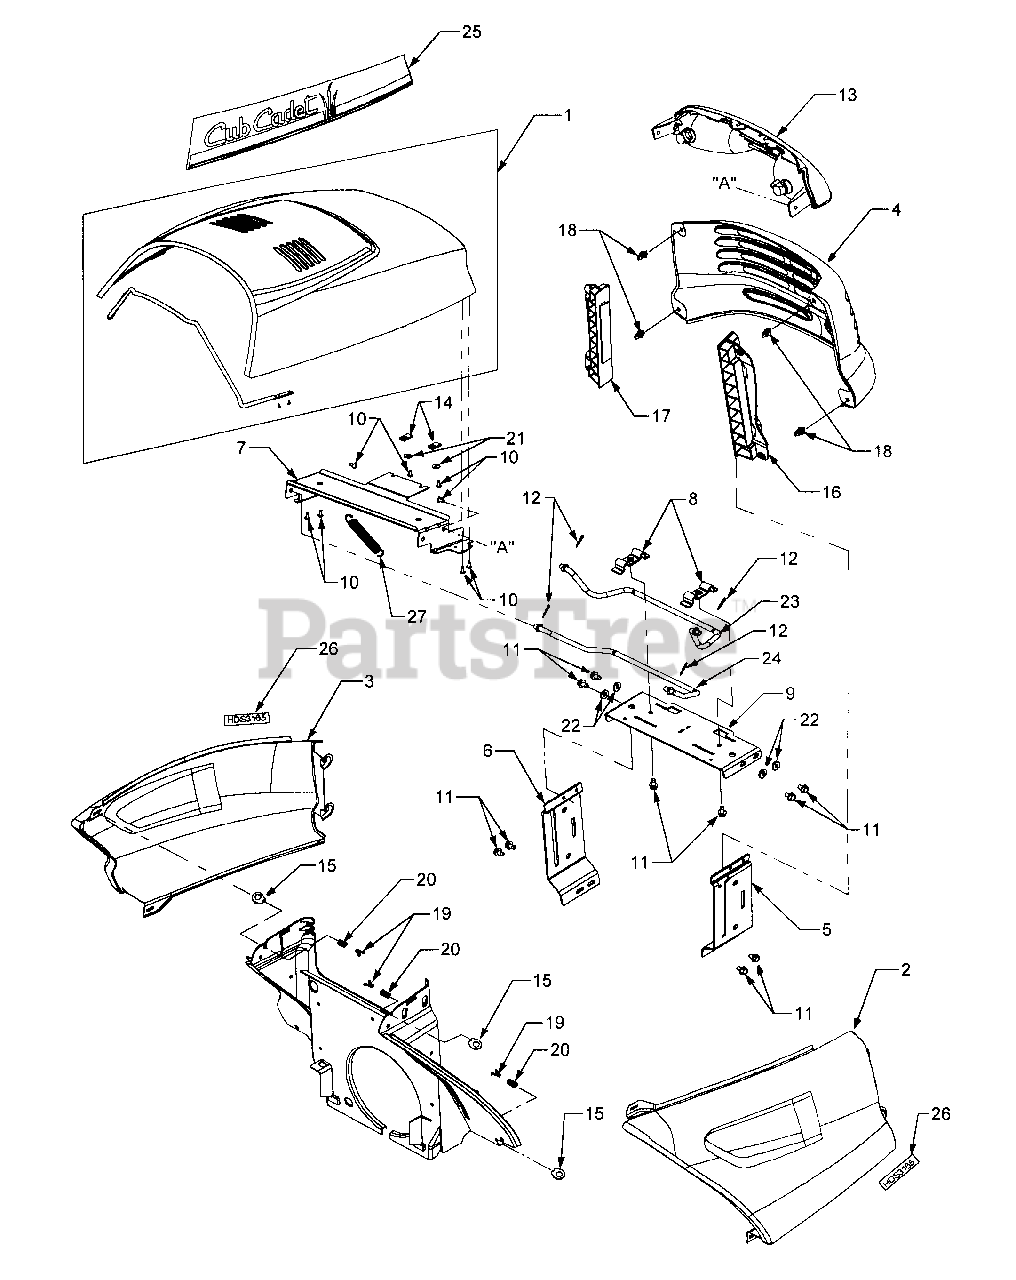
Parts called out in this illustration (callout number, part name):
1	Hood w/Support Rod Assembly
2	Side Panel, RH
3	Side Panel, LH
4	Grille, Series 3000
5	Support, Grille - RH
6	Support, Grille - LH
7	Bracket, Upper Hood
8	Bracket, Rod Retainer
9	Support, Hood
10	Screw, Truss Hd, Tapp, #10-16 x .5
11	Screw, Hex Wash. Hd. Tapp 5/16-18 x .5
12	Pin, Internal Cotter
13	Headlight Assembly
14	Nut, U-type Speed, #10
15	Latch, 1/4 Turn
16	Mount, Side Panel/Grille RH
17	Mount, Side Panel/Grille LH
18	Fastener, Grille Mount
19	Clip, Spring
20	Spring, Compression
21	Washer, Flat, .194 x .62 x .063
22	Washer, Flat, .344 x .75 x .120
23	Rod, Upper Hood
24	Rod, Upper Hood
25	Graphic, Hood - RH
26	Graphic, HDS 3165
27	Spring, Extension
